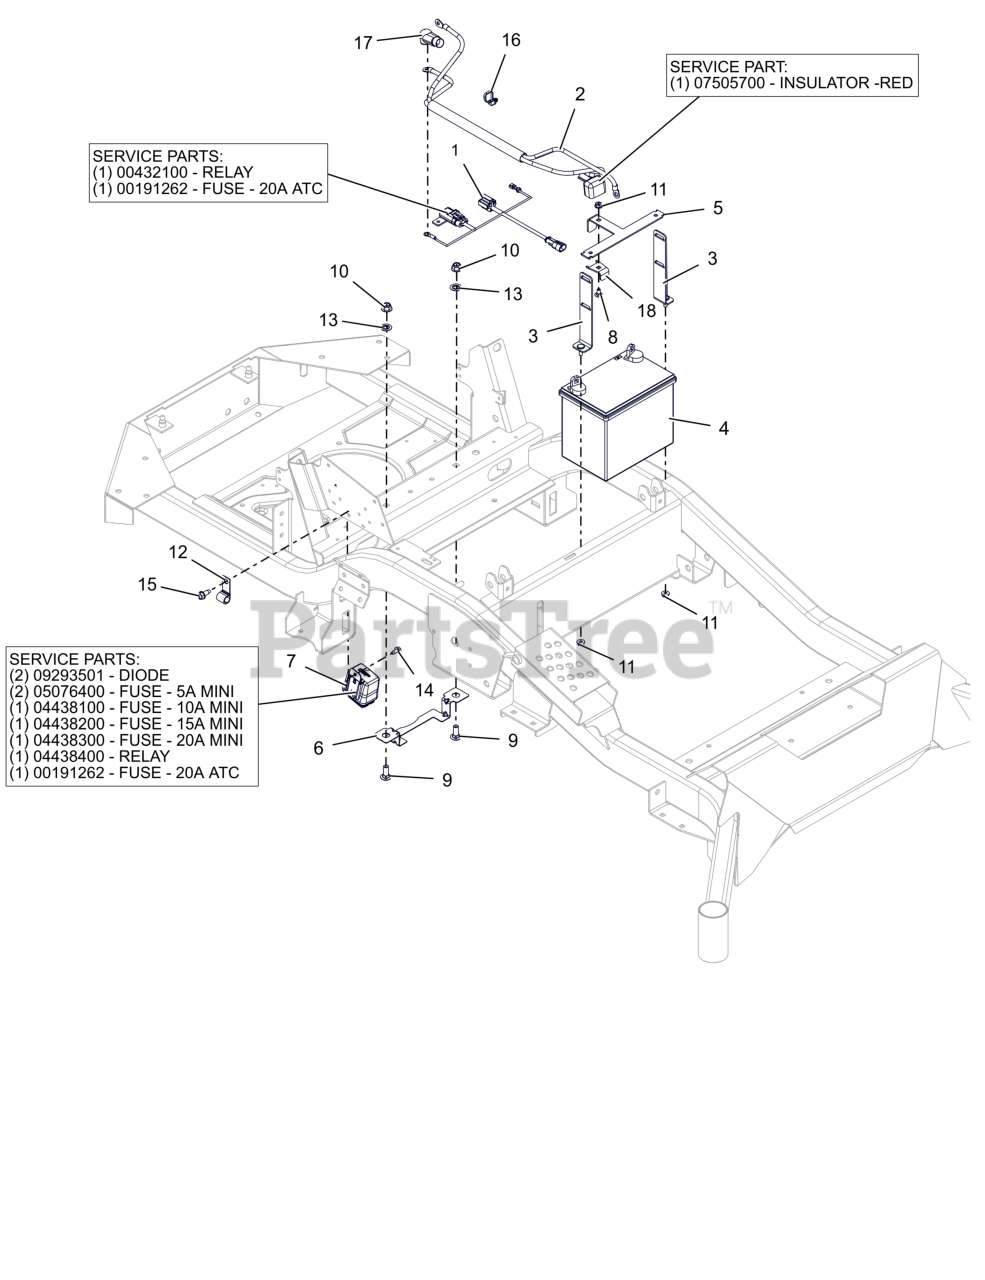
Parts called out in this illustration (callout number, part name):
1	HARNESS, STARTER ADAPTOR
1	RELAY,SEALED W/DIODE
1	FUSE, 20 AMP BLADE S/O
2	HARNESS, BATTERY HD
2	INSULATOR
3	WMT-BATT MNT HOLD DOWN FORMED
4	BATTERY, 300 CCA 10U1L
5	BRKT- BATTERY HOLD DOWN
6	GUARD, ELECTRICAL HARNESS
7	HARNESS, WIRE
7	DIODE, CONNECTOR SHELL
7	FUSE, 5 AMP MINI-ATC
7	FUSE,10 AMP MINI-ATC
7	Fuse, 15 AMP MINI-ATC
7	FUSE,20 AMP MINI ATC
7	RELAY,MICRO5 TERML W/RESISTOR
7	FUSE, 20 AMP BLADE S/O
8	BLT, RHSN .25-20X.500 G5 ZCC
9	BLT, RHSN .38-16X1.00 G5 ZCC
10	NUT,NYL-FLG .38-16 GF ZCC
11	NUT-LK-TOP-FLG .250-20 GF ZCC
12	J-CLAMP
13	WSHR, RETAINING .35X.88X.03 NYL
14	SCR-TAP .25-20X.50 HWH ZCC
15	SCR,TAP .312-18X.75 HWH TR ZCC
16	CABLE TIE W/ TREE (.25 HOLE)
17	BOOT, .65ID POS
18	BRKT, BATTERY HOLD
